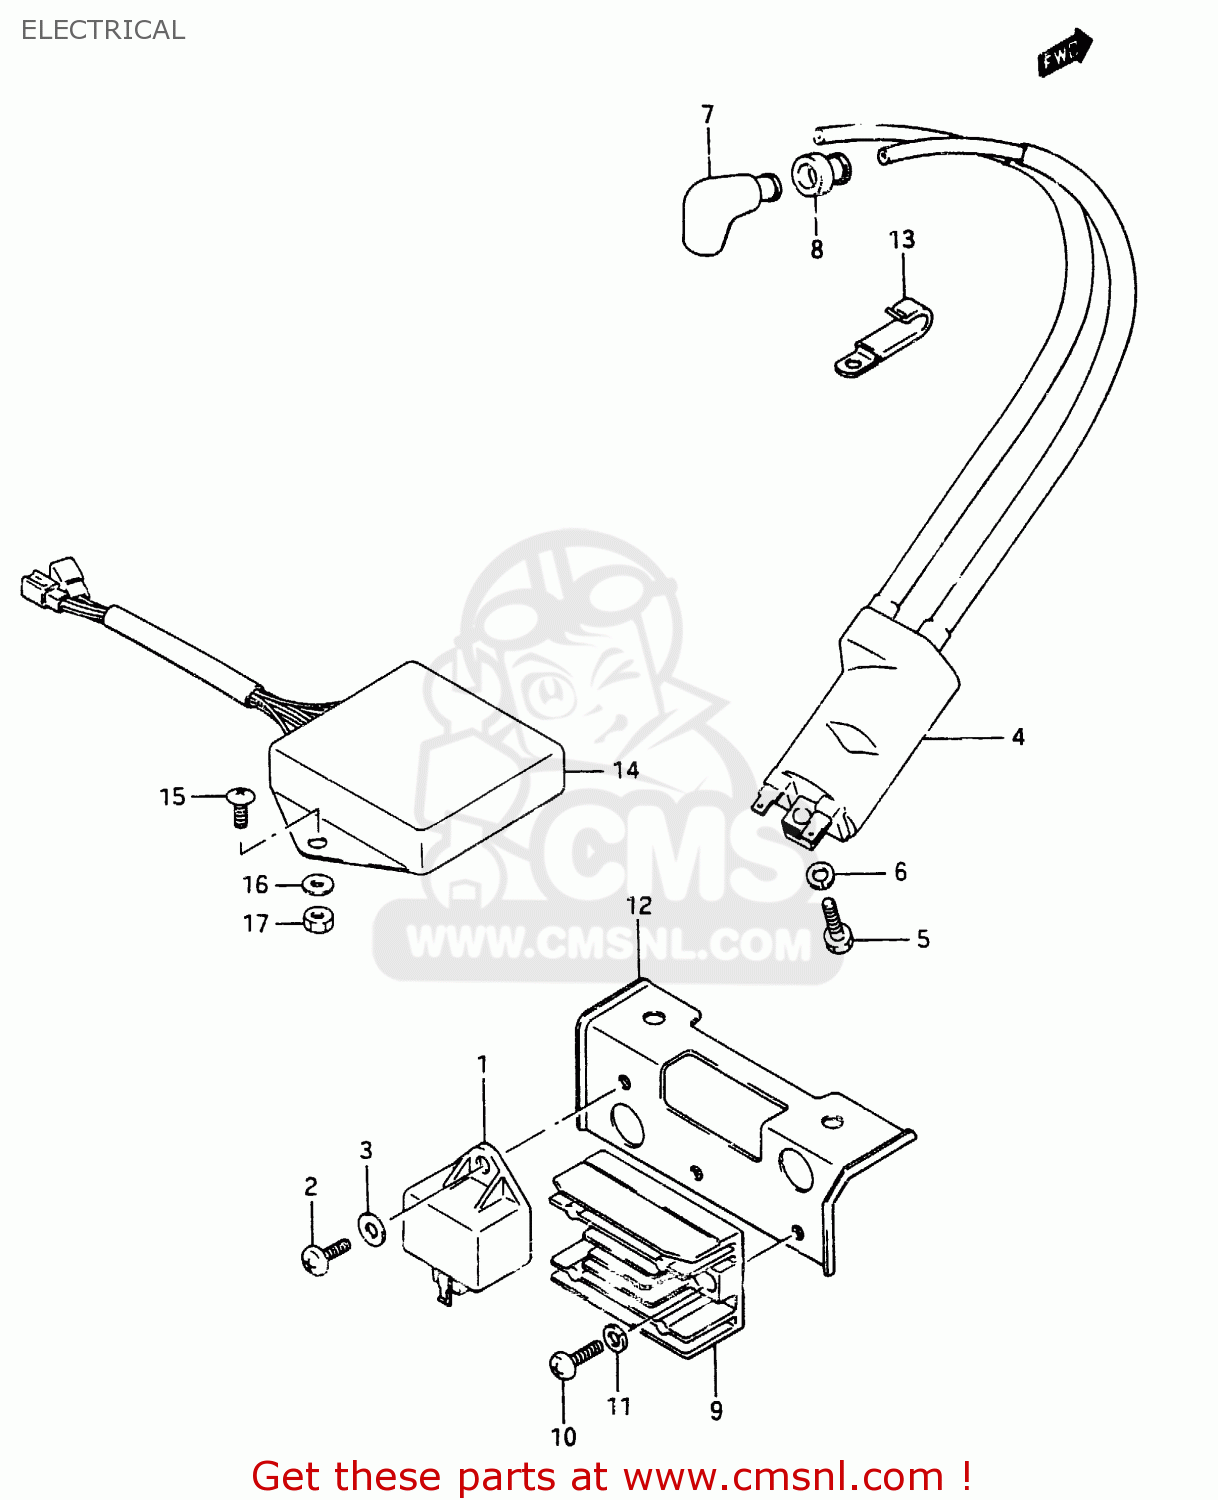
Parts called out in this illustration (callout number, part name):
1	CDI UNIT
2	SCREW
3	WASHER, LOWER
4	COIL ASSY,IGNITION
5	BOLT(6X20)
6	WASHER,LOCK
7	CAP,SPARK PLUG
8	SEAL,SPARK PLU
9	RECTIFIER ASSY
10	SCREW
11	WASHER,LOCK
12	HOLDER, ELECTRIC PARTS
13	CLAMP
14	UNIT, EXHAUST VALVE CONTROL
15	SCREW
16	WASHER, LOWER
17	NUT
